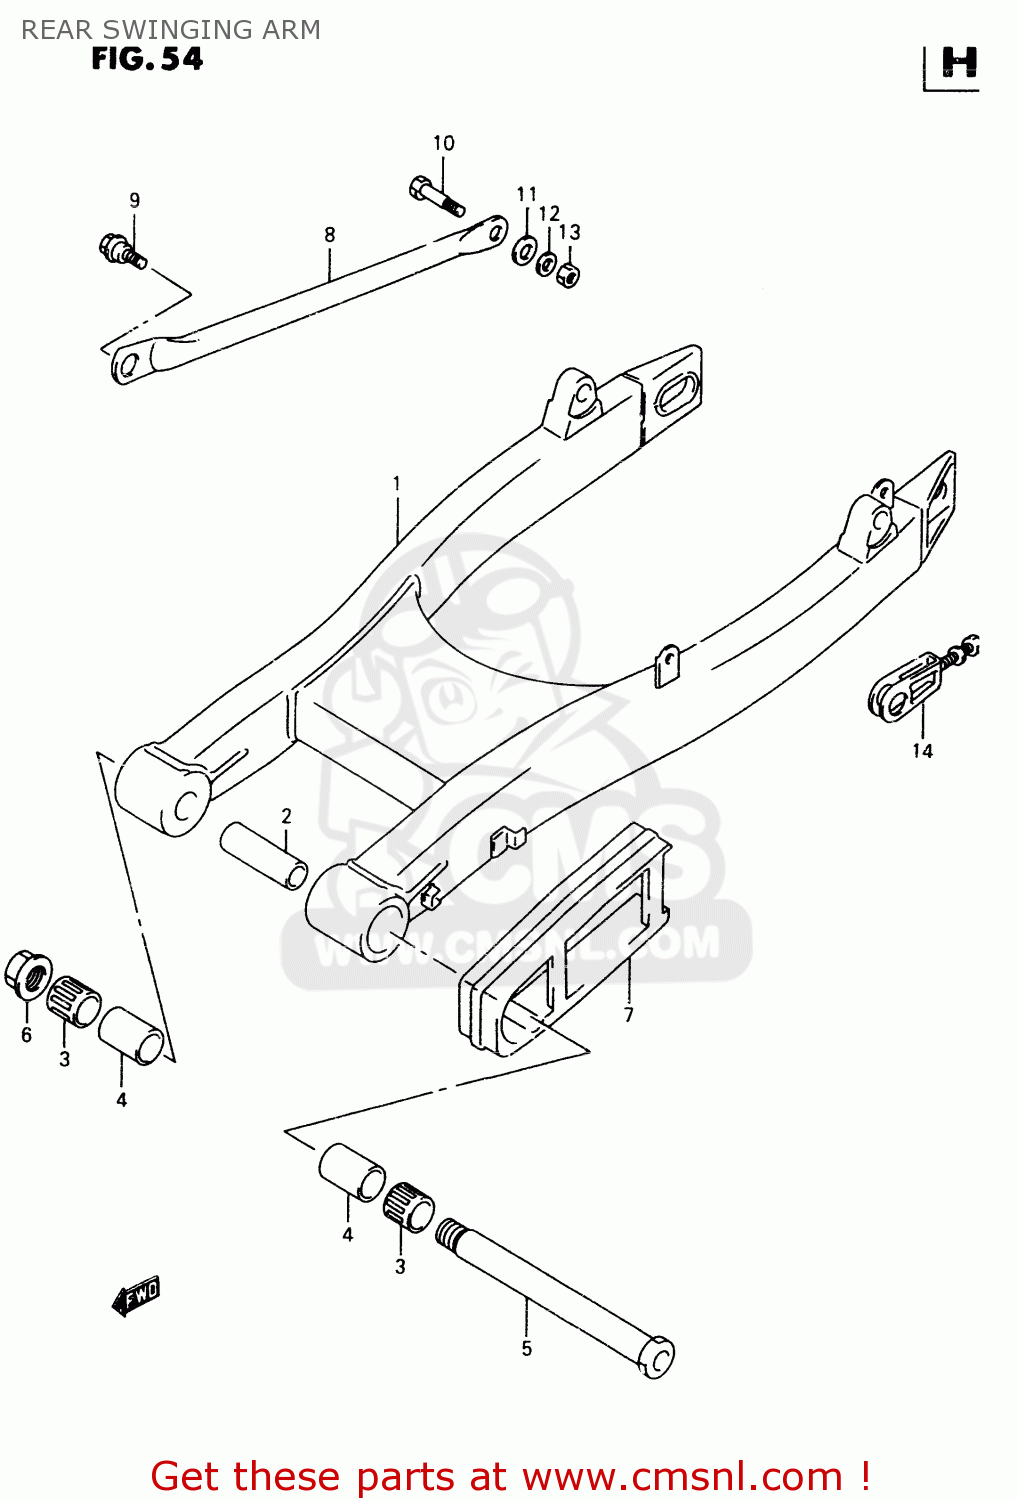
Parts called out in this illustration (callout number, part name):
1	SWINGINGARM,RR
2	SPACER,RR SWGARM PIVOT CTR
3	BEARING(25X33X35)
4	SPACER,RR SWGARM PIVOT
5	SHAFT,RR SWINGINGARM PIVOT
6	NUT ,18MM
7	BUFFER,CHAIN TOUCH DEFENSE
8	TORQUE LINK,RR
9	BOLT(10X30)
10	BOLT(10X41)
11	CUSHION
12	WASHER (10X20X2.3)
13	NUT
14	ADJUSTER ASSY,CHAIN
